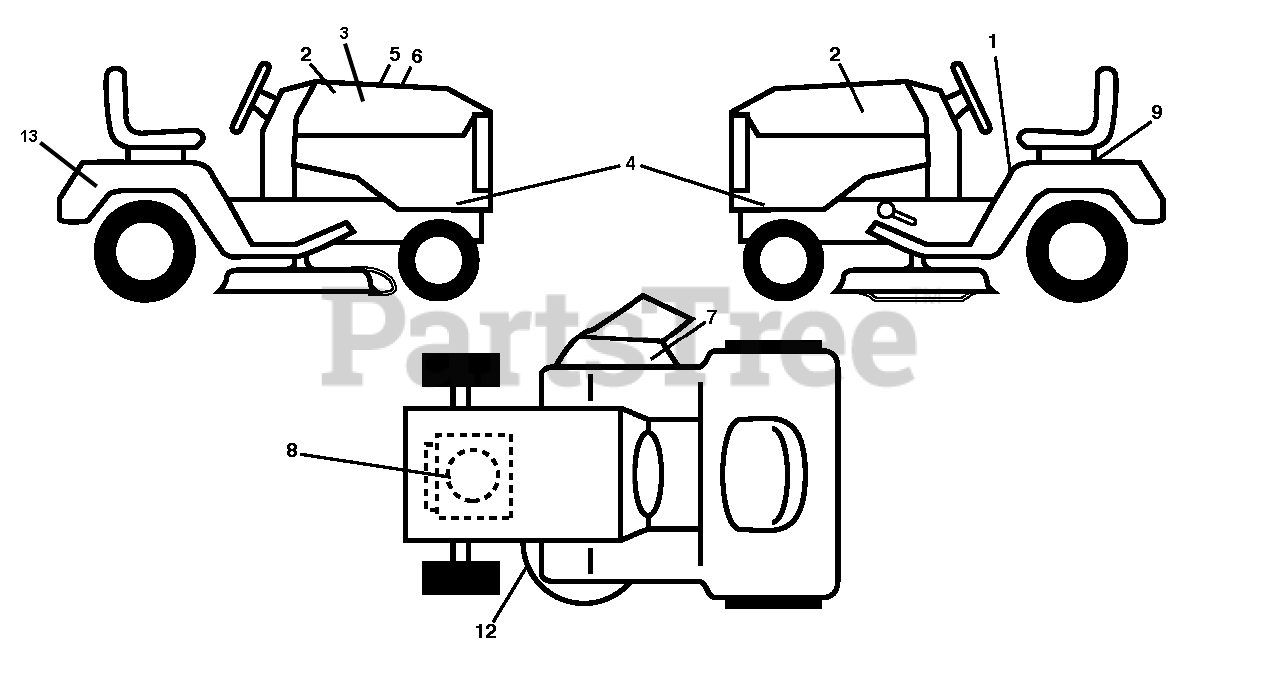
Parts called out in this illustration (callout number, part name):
1	DECAL.FENDER.WARNING.ENGLISH
1	DECAL.WARNING.2007.ENG/FR
2	RP.DECAL.BADGE.170MM.TEXTLOGO
3	DECAL.RPL.TLW.M33.42.VATR
4	DECAL.SDPNL.YTA18542.SET.HUSQ
5	DECAL.WARNING.CUST.RESP.E85.
6	DECAL.RPL.BSM33.INTK.TLW.42
7	DECAL, DECK DEFLECTOR, WARNING
8	DECAL.ENG.BS.18.5INTK.381713
9	DECAL BTRY SYMBOLS
12	DECAL.V-BELT.SCH.42/46"MEC/ELE
13	DECAL.FENDER
